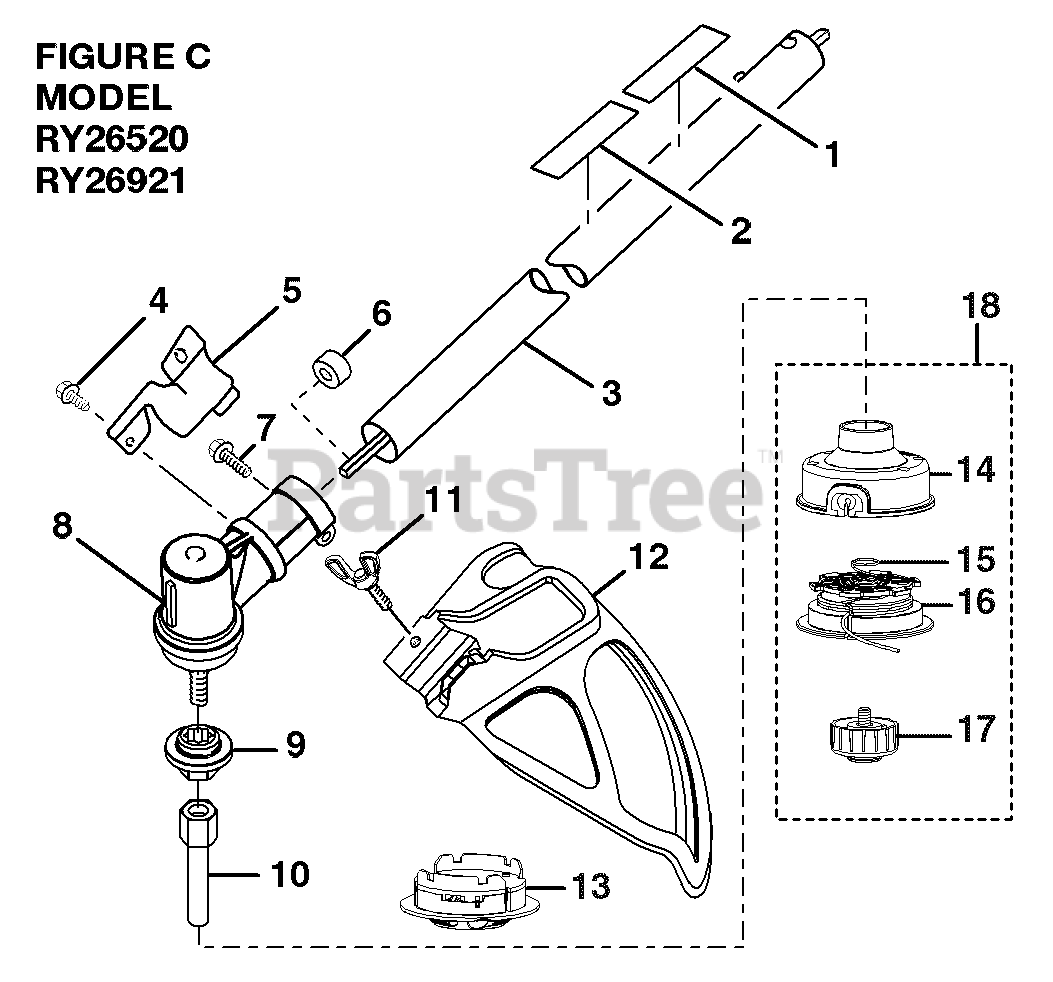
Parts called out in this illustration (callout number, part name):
1	Expand-it Label
2	Warning Decal
3	Straight Shaft Assembly
4	Screw (10-24 x 5/8 in.)
5	Clamp
7	Screw (1/4-20 x 1-1/4 in.)
8	Gear Head
9	Flanged Washer
11	Wing Screw (1/4-20 x 1-1/4 in.)
12	Grass Defector Assembly
13	Dual Spool™ Fixed Line String Head Insert
14	Bump Feed String Head
15	Spring
16	Bump Feed Spool
17	Spool Retainer
18	Bump Feed String Head Assembly
